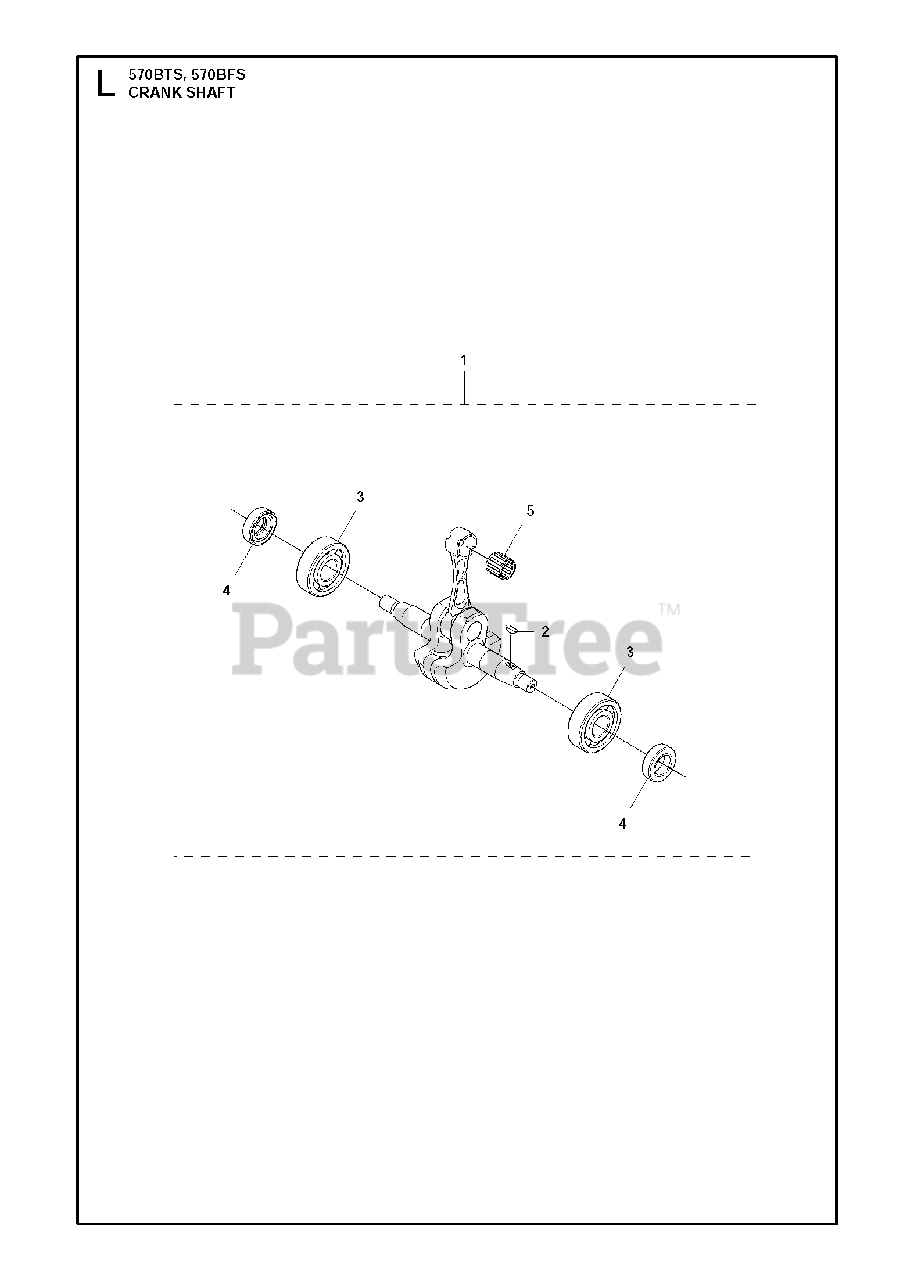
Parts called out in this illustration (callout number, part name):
1	CRANKSHAFT
2	KEY
3	BALL BEARING
4	SEAL
5	BEARING
